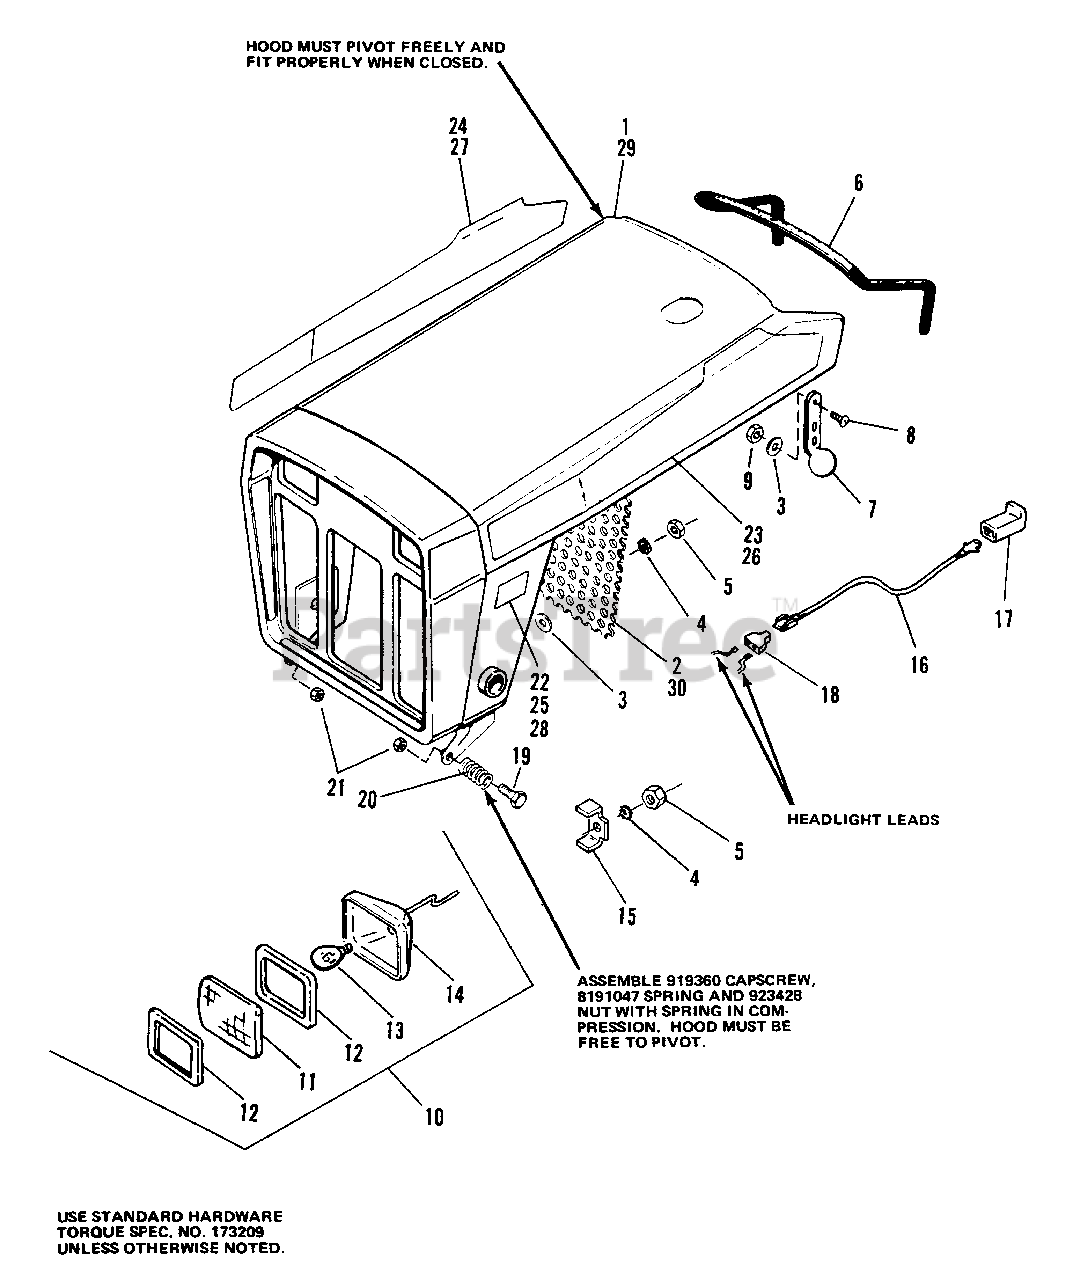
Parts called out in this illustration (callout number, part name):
1	HOOD & GRILLE ASSY (7012 & 7016 Only)
2	SCREEN, Grille (7012 & 7016 Only)
3	WASHER, Special
4	LOCKWASHER, Ext. Tooth, No. 10
5	NUT, Hex, Mach., No. 10-24
6	MOULDING, Hood
7	STRAP, Hood
8	SCREW, Truss Hd., No. 10-32 x 1/2
9	LOCKNUT, Hex, No. 10-32
16	WIRE ASSY
17	BODY, Connector
18	CONNECTOR, Insulated
19	CAPSCREW, Hex, Hd., 3/8-16 x 1-1/2
21	NUT, Hex, 3/8-16
22	DECAL, 7012 Hydrostatic
23	DECAL, Hood, Landlord, L.H. (7012 Only)
24	DECAL, Hood, Landlord, R.H. (7012 Only)
25	DECAL, 7016 Hydrostatic
26	DECAL, L.H. Hood, Sovereign (7016 Only)
27	DECAL, R.H. Hood, Sovereign (7016 Only)
28	DECAL, 7018 Hydrostatic
29	HOOD & GRILLE ASSY (7018 Only)
30	SCREEN, Grille (7018 Only)
